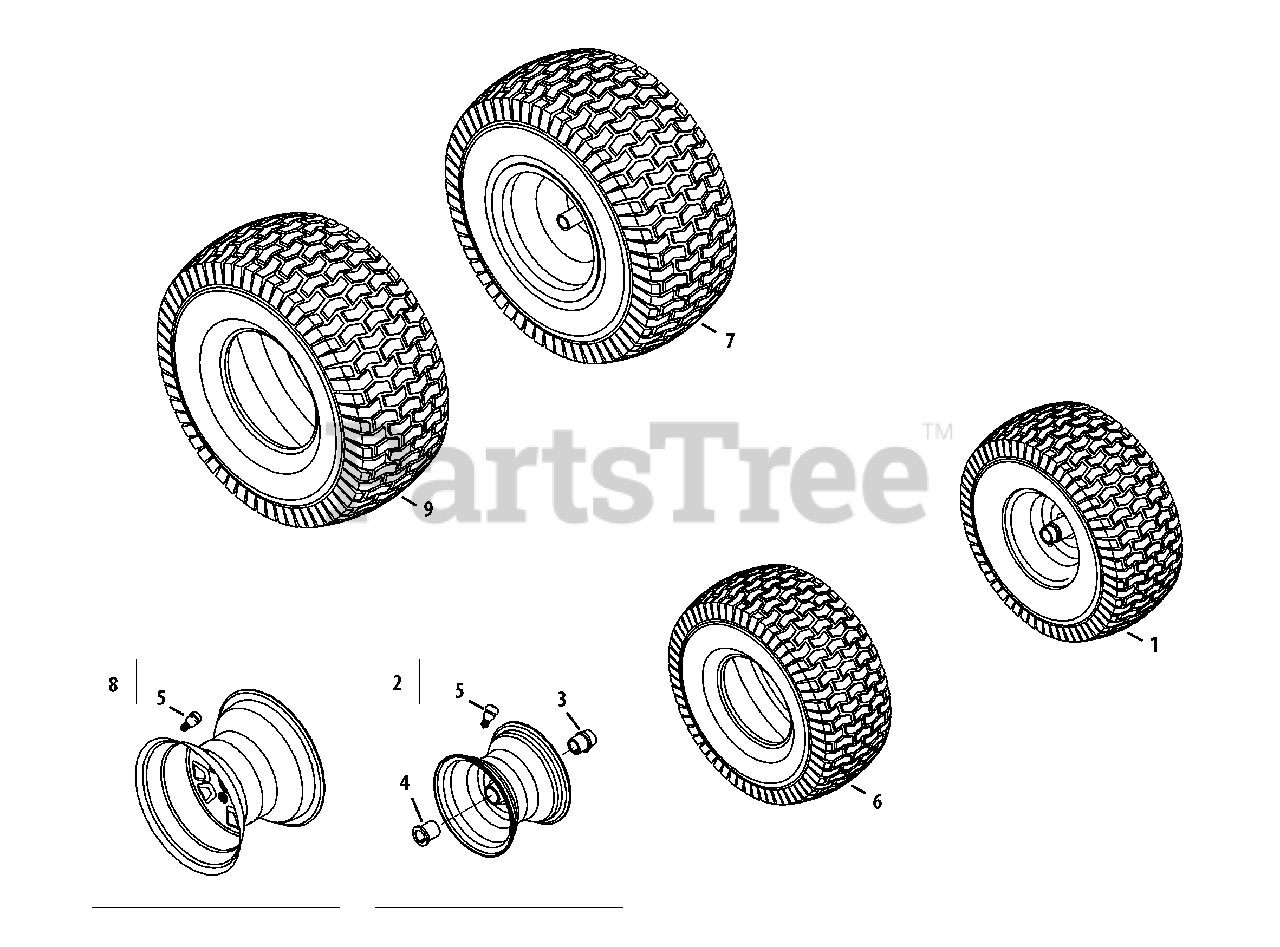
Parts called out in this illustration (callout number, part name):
1	Wheel Ass’y, Complete, 16 x 6 x 5.8
2	Rim Ass’y, 8.0 x 5.3, Flange Bearings
3	Bearing, Flange, .760 ID w/ Fitting
4	Bearing, Flange, .760 x 1.00 x 1.20
5	Valve, Tubeless Air
6	Tire, 15 x 6.5 x 8 Sq Shoulder
7	Wheel, Complete, 22 x 9.5 x 12
8	Rim Ass’y, 12.0 x 7.0
9	Tire, 22 x 9.5 x 12 Sq Shoulder
